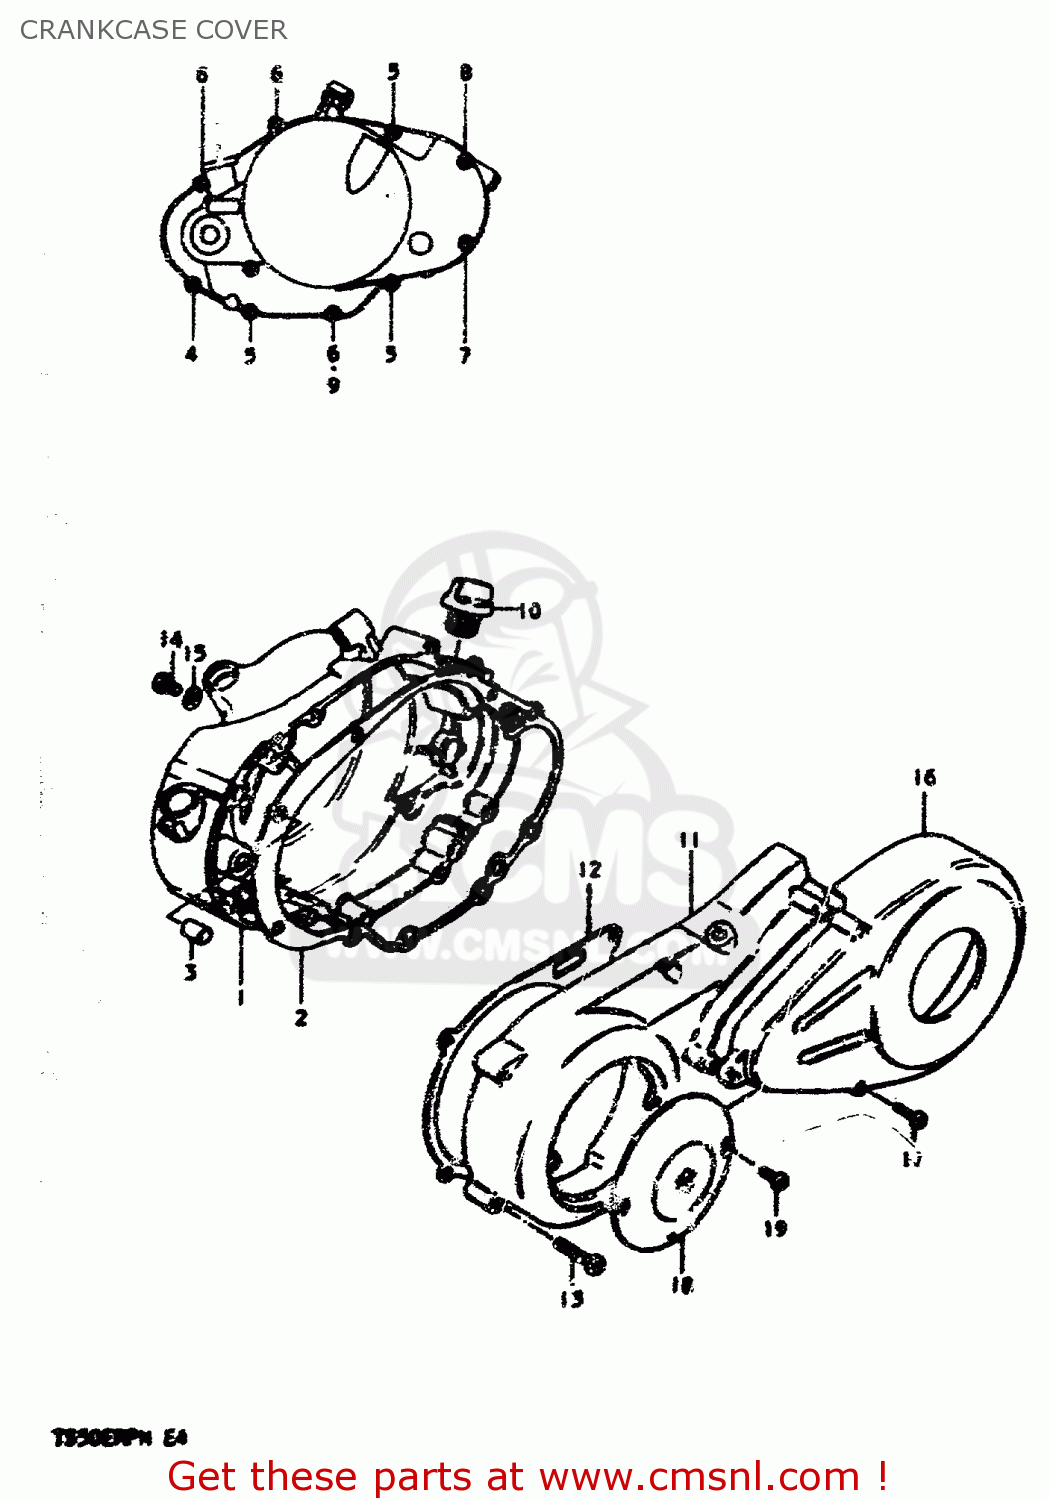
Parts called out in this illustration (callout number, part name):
1	COVER SET,CLUTCH
2	GASKET,CLUTCH COVER (MCA)
3	PIN
4	SCREW
5	SCREW 6X30
6	SCREW
7	SCREW
8	SCREW 6X60
9	GASKET(6.2X11X1).2 (NAS)
10	PLUG
11	COVER, MAGNETO
12	GASKET,MAGNETO COVER (NAS)
13	SCREW (6X35)
14	SCREW(6X10)
15	GASKET(6.2X11X1) (NAS)
16	COVER, CYCLE CHAIN
17	SCREW
18	CAP,MAGNETO INSPECTION
19	SCREW
